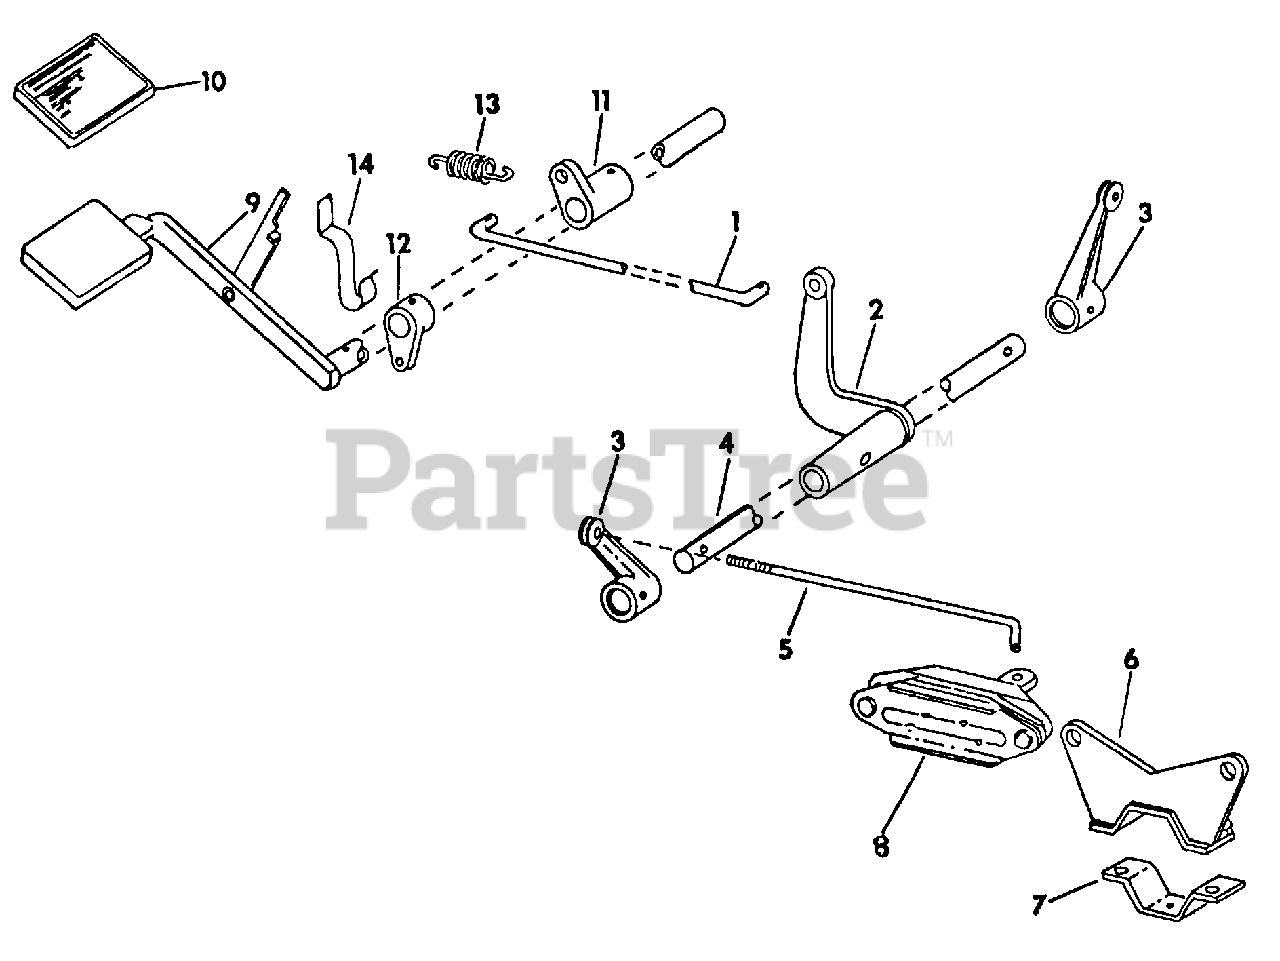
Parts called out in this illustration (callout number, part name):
2	Lever Assy, Brake
4	Shaft, Brake Pivot
6	Bracket Assy, Caliper
7	Flange, Caliper Mounting
8	Caliper Assy, Brake LH
9	Pedal Assy, Clutch
10	Pad, Pedal
11	Lever Assy, Brake Rod
12	Lever Assy, Neutral Return
13	Spring, Brake Pedal Return
14	Spring, Safety Switch Operating
